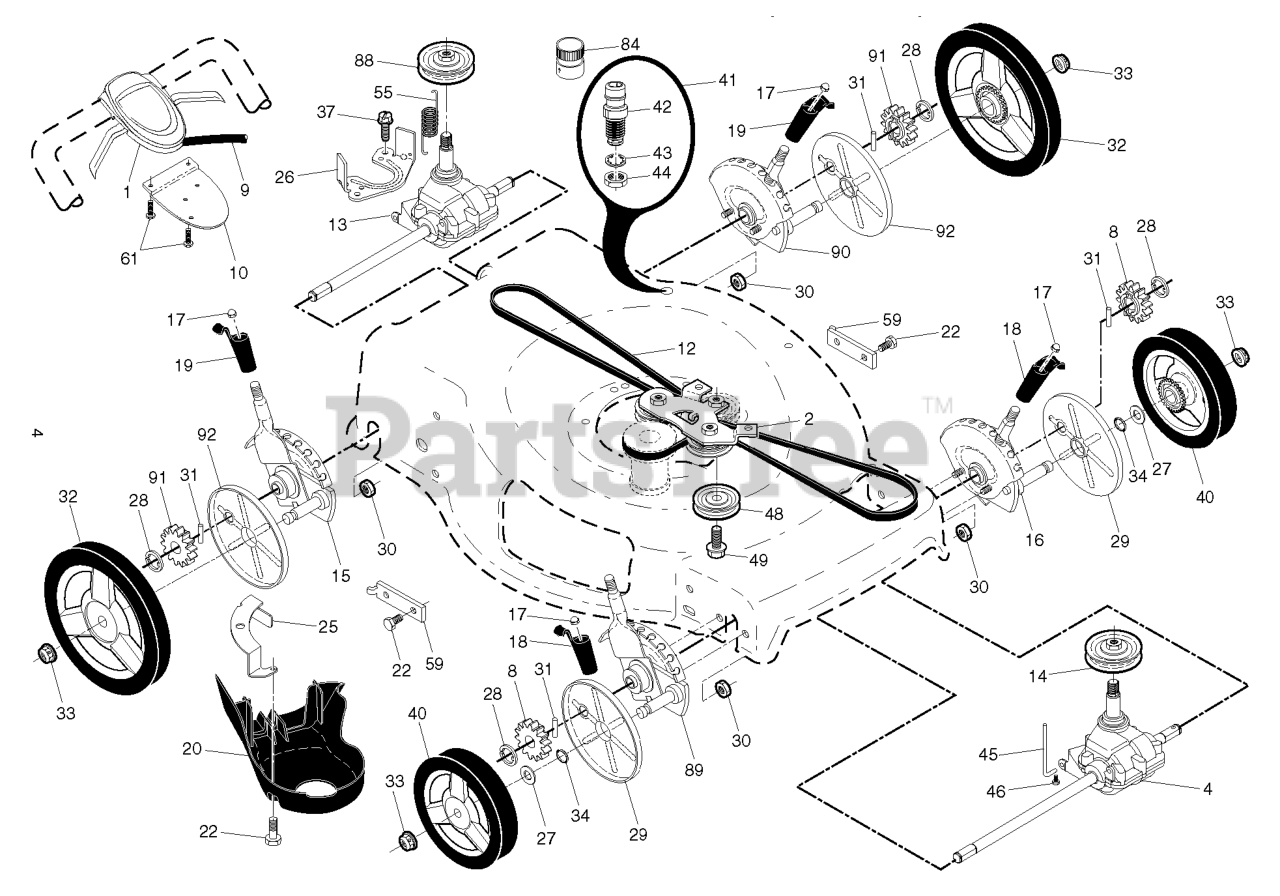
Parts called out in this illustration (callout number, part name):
1	CONTROL.AW2.22+RG.BS.GEN.BK/BK
2	BRACKET.ASM.AWD.BZP.BLACK
4	RP.TRANSMISSION.22+.AWD.FRONT
8	PINIION.14.TOOTH.RGD
9	CABLE.DRIVE.RWD.WALK.
10	BRACKET.DRIVE.CONTR.GEN2.BLACK
12	BELT.DRIVE.AWD.13 ZINC DUSTED
13	TRANSMISSION.ASM.22+AWD.REAR
14	RP PULLEY.PM.22+AWD
15	KIT.ADJ.22+QP.RR.HW.BLK.ZINC
16	KIT.ADJ.22+QP.LF.BLACK.ZINC
17	NUT.PUSH.156
18	KNOB.ADJUSTER.LW.BLK
19	KNOB.ADJUSTER.REAR.BLACK
20	COVER.REAR.DRIVE.22+2013
22	BOLT.5/16HEX.WHS.HD
25	BRACKET.DRIVE.COVER.RGD.BZP
26	BRACKET.TRAN.BELTKEEPER.22+RGD
27	WASHER FLUT
28	E-RING 7/16 RE
29	COVER.DUST.WHEEL.INNER.WALK
30	NUT.FLANGE.1-4-20-SERR
31	PAWL, DRIVE
32	WHEEL.11.H3SP.AWD.BB.460.BU2
33	NUT.HEX.FLANGE.3/8-16.LO(3 2)
34	O-RING..070X.487.NEOPRENE
40	WHEEL.8".AWD.3SP.EXT.DR.GREY
41	KIT.WASH-OUT.PORT.ZINC.WALK
42	WASHOUT.PORT.ZINC.RGD.22+
43	WASHER.LOCK.INTERNAL.TOOTH
44	LOCKNUT.HEX.WITH.O-RING
45	BRACKET.AWD.FRONT.BELT.KEEPER
46	SCREW.HI-LO. 5/16 X 1.00
48	RP PULLEY.IDLER.ASM
55	SPRING.RETURN.AUTO.
59	BRACKET.SUPPORT.22+RWGD.BZP
61	SCREW, PHILLIPS HEAD 10 X 5/8
84	COUPLING.QUICK CONNECT
89	KIT.ADJ.22+QP.RF.BLACK.ZINC
90	KIT.ADJ.22+QP.LR.HW.BLK.ZINC
91	PINION.16.TEETH.HW.AWD.REAR
92	COVER.DUST.WHEEL.HW.AWD.REAR
